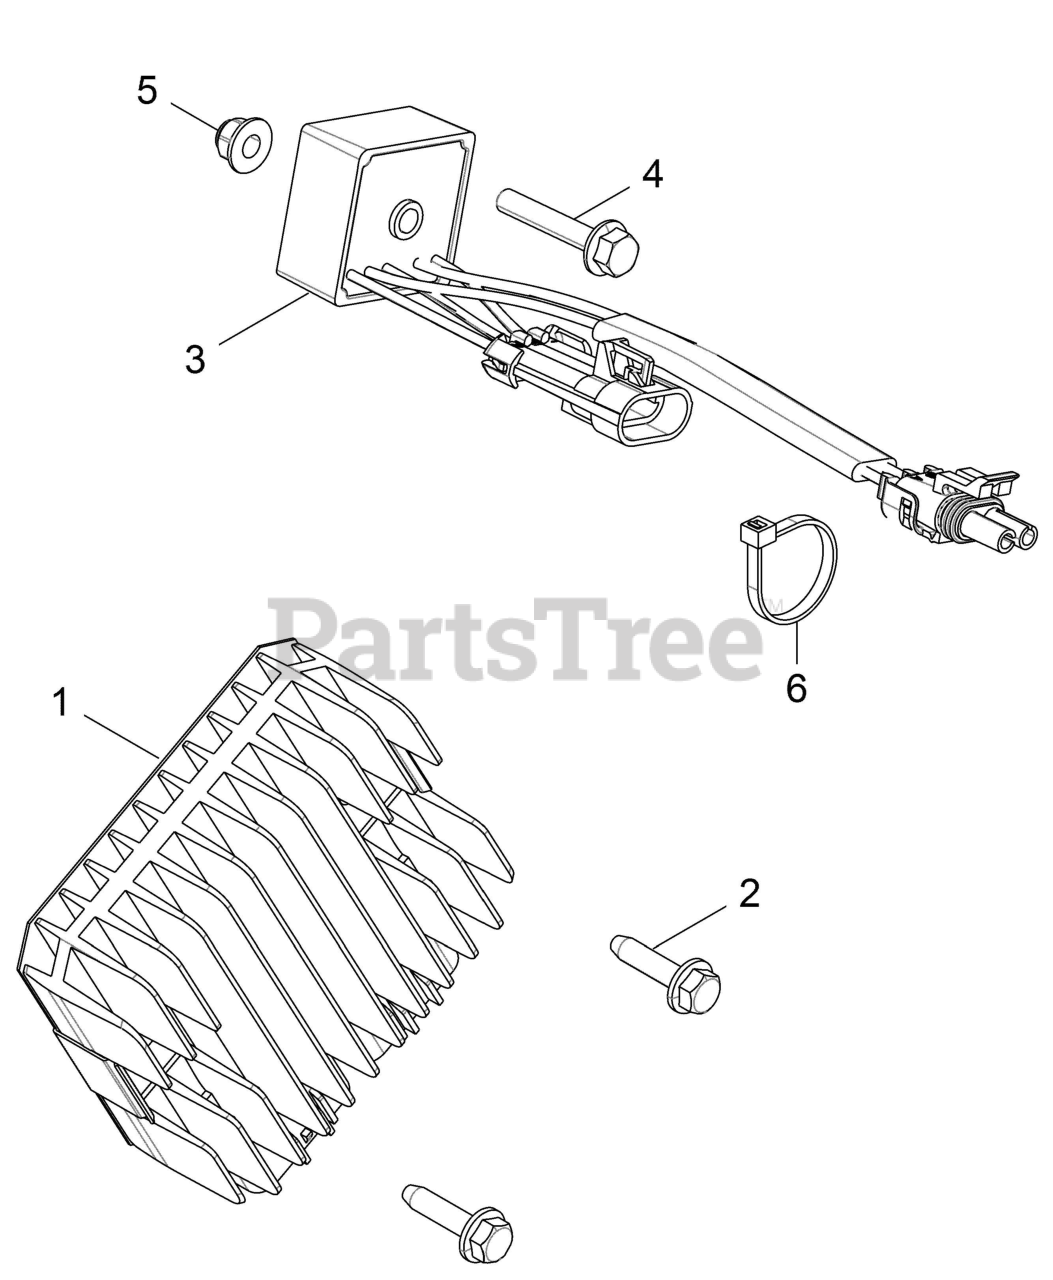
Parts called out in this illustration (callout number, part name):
1	REGULATOR-3PH,50A,SERIES,HISPD
2	SCR-TFHFL-M6X1.0X25,ZOD
3	RELAY, SOLID STATE,9A,LONG LD
4	BOLT-M6X1.0X35,HXFLG/SH-OLV D
5	NUT-M6X1.0,FLG-NYLOC-OLIVE D
6	CABLE TIE (10)
